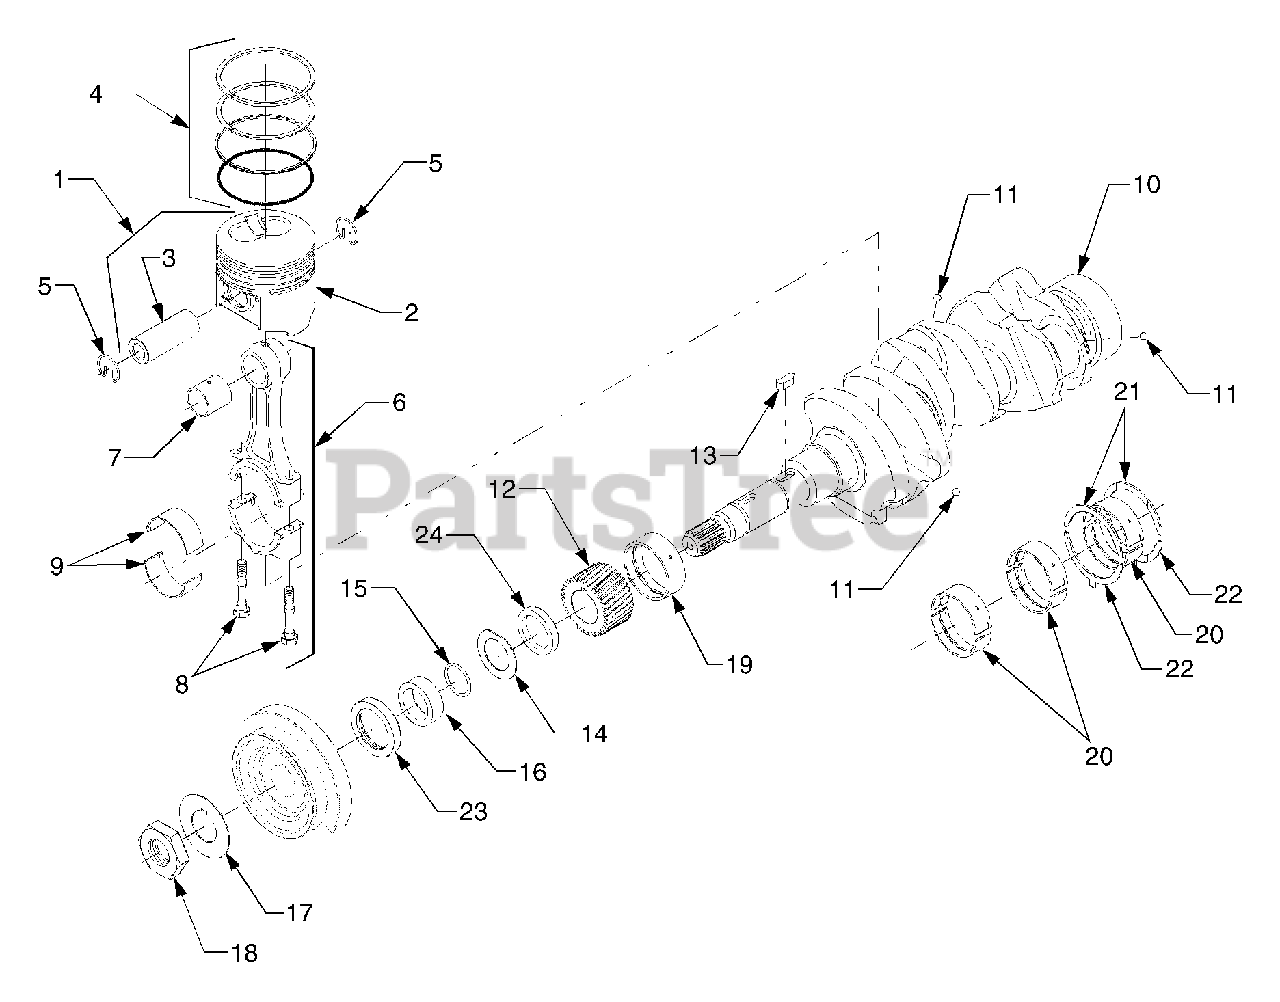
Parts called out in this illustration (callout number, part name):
1	Piston Ass'y
2	Piston
4	Piston Ring Ass'y
6	Connecting Rod Ass'y
7	Bush, Piston Pin
8	Bolt, Connecting Rod
9	Metal, Crank Pin
10	Crank Shaft Ass'y
12	Gear, Crankshaft
16	Collar, Crankshaft
17	Washer, Crankshaft
18	Nut, Crankshaft
19	Metal, Crankshaft 1
20	Metal, Crankshaft 2
21	Metal, Side 1
22	Metal, Side 2
